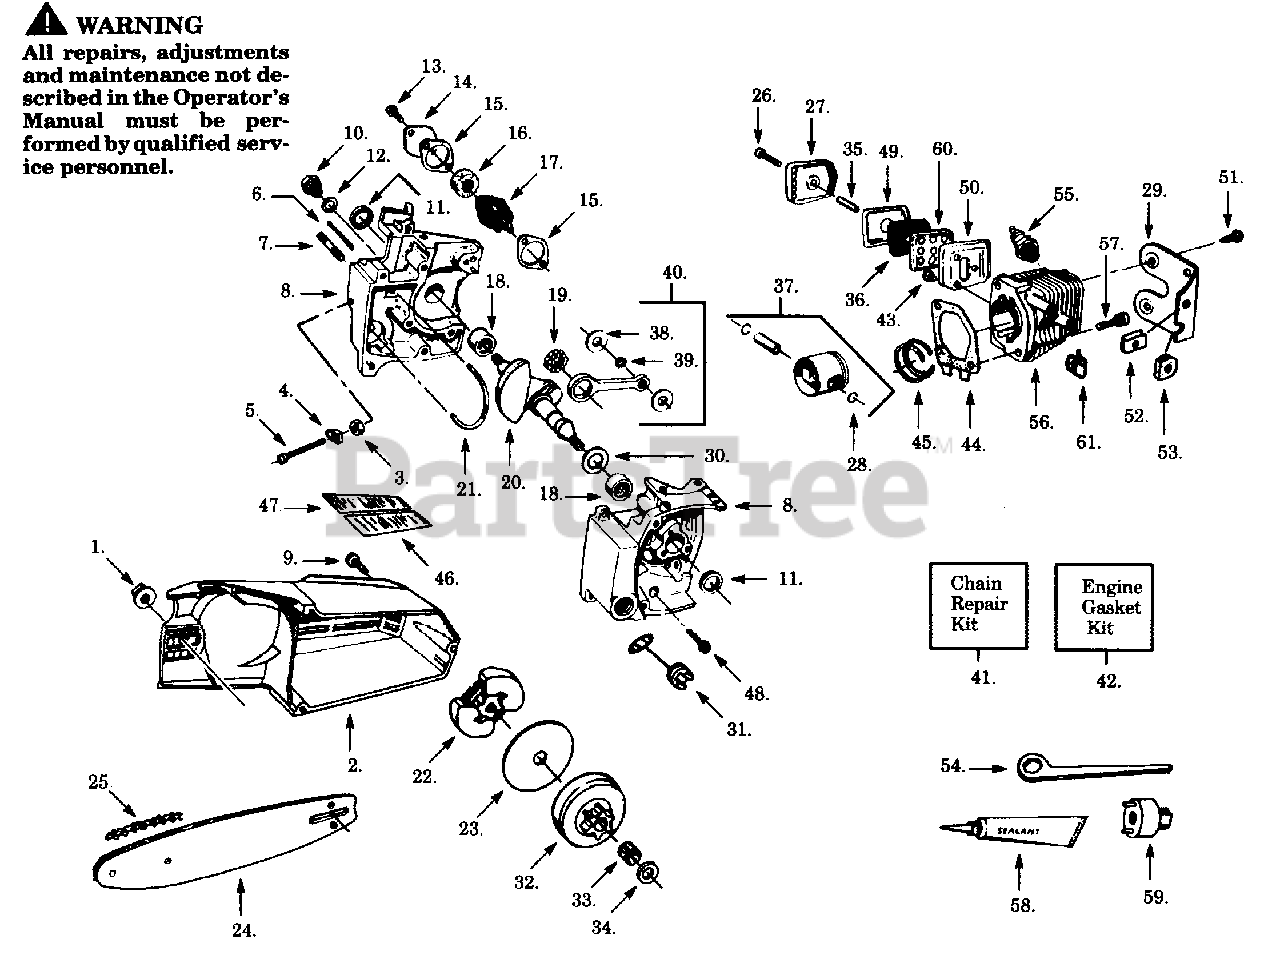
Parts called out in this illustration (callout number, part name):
1	Bar Mounting Nut
2	Bar Clamp
4	Bar Adjust Pin
5	Screw
6	Oil Tank Vent Pin
7	Bar Mounting Stud
8	Crankcase Ass'y.
10	Check Valve Kit
11	Crankshaft Seal
12	Check Valve Gasket
15	Metering Body Gasket
16	Oil Filter (Foam)
17	Oil Pump Ass'y.
18	Crankshaft Bearing
19	Roller Bearing
20	Crankshaft
21	Oil Discharge Line
22	Clutch Ass'y. Kit
23	Clutch Washer Kit (Outside)
24	Guide Bar-16"
25	Chain-16"
27	Muffler Cover
28	Piston Pin Retainer
29	Rear Mount Bracket
30	Thrust Washer
31	Oil Cap Ass'y.
32	Clutch Drum
33	Clutch Bearing
34	Clutch Spacer-Inside
35	Muffler Spacer
36	Muffler Screen
37	Piston Kit
39	Bearing Rod Top
40	Connecting Rod Assy
41	Chain Repair Kit
42	Engine Gasket Kit
44	Cylinder Gasket
45	Piston Ring
46	Inst. Decal Left
47	Inst. Decal Right (Not a serviceable part)
49	Muffler Baffle-Outer
50	Muffler Body
52	Speed Nut
54	Bar Wrench
55	Spark Plug
56	Cylinder
58	Crankcase Sealant
59	Clutch Tool
60	Muffler Baffle-Inner
61	Wire Clip
